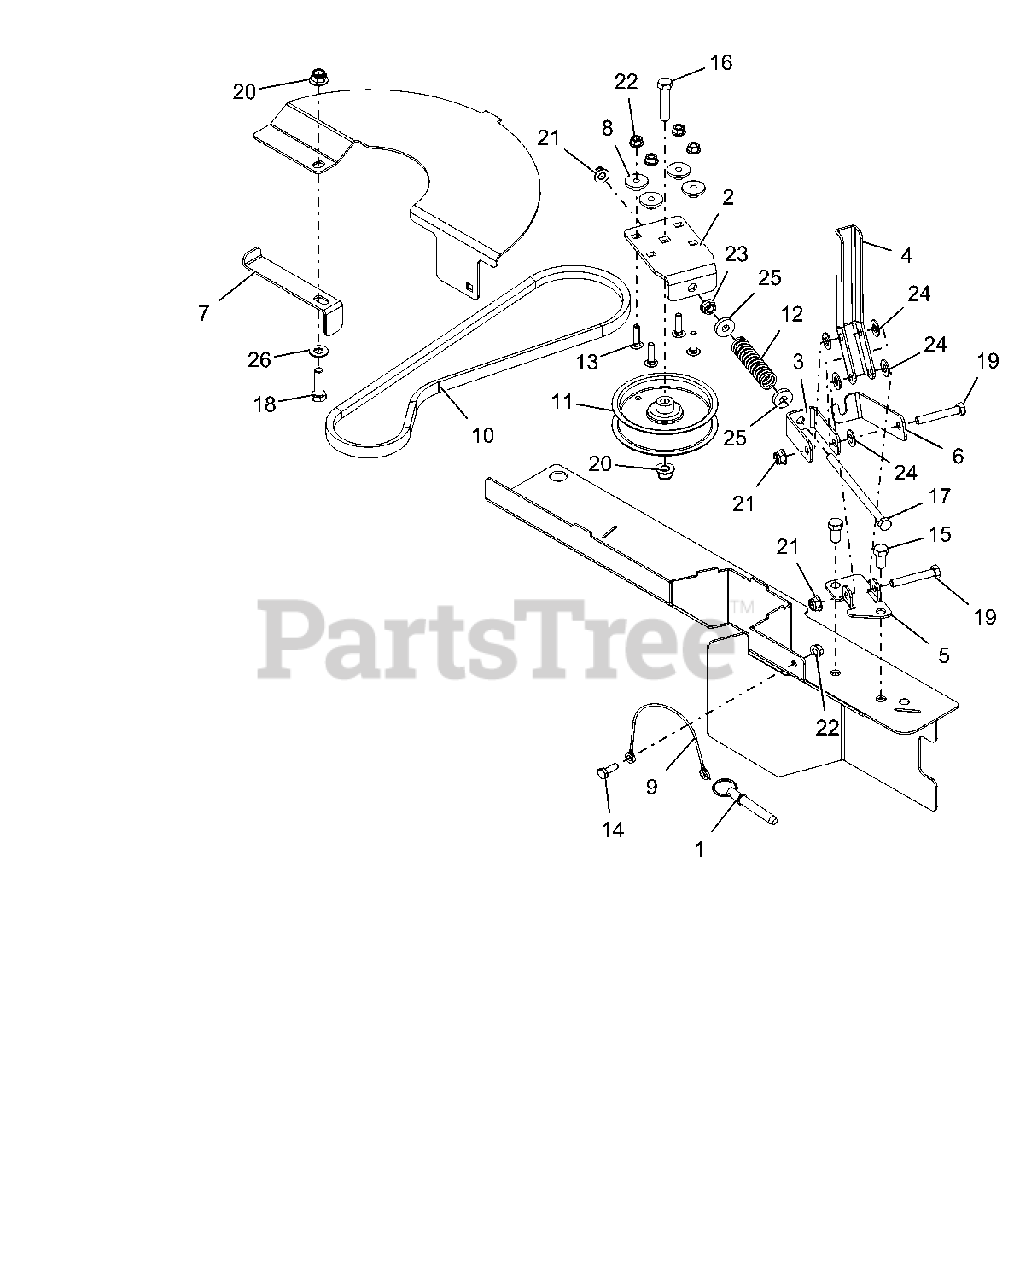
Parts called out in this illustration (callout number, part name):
1	PIN, SPRING BALL .375OD X 1.50
2	BRACKET, ADJUSTABLE IDLER
3	LINK - IDLER RELEASE
4	LEVER - IDLER RELEASE
5	MOUNT - IDLER RELEASE LEVER
6	LOCK - IDLER RELEASE LEVER
7	FINGER - BELT
8	BSHG-FLG .265X.477X.375X1.00
9	CABLE, 12.0 LANYARD, NYLON
10	V-BELT, 4L WRAPPED CLUTCHING
11	PULLEY, IDLER 4.00
12	SG-COMP .092X.77X3.13 WLD 36
13	@BLT-RDHDSQNK .25-20X1.00 G5YZ
14	@BLT-HEX .25-20X.75 GR5 YWZC
15	@BLT-HEX .38-16X.75 GR5 YWZC
16	@BLT-HEX .38-16X1.75 GR5 YWZC
17	@BLT-HEX .31-18X5.50 GR5 YWZC
18	@BLT-HEX .38-16X1.25 GR5 YWZC
19	@BLT-HEX .31-18X2.00 GR5 YWZC
20	@NUT-LK-NYL-FLG .38-16 YWZC
21	@NUT-LK-NYL-FLG .31-18 YWZC
22	@NUT-LK-TOP-FLG .25-20 YWZC
23	@NUT-SPNLK-FLG .312-18 YWZC
24	WSHR-FL-NY .375X.75X.060
25	WSHR-FL-STL .328X.87X.179 YWZC
26	@WSHR-FL-STL.406X.812X.065 YWZ
